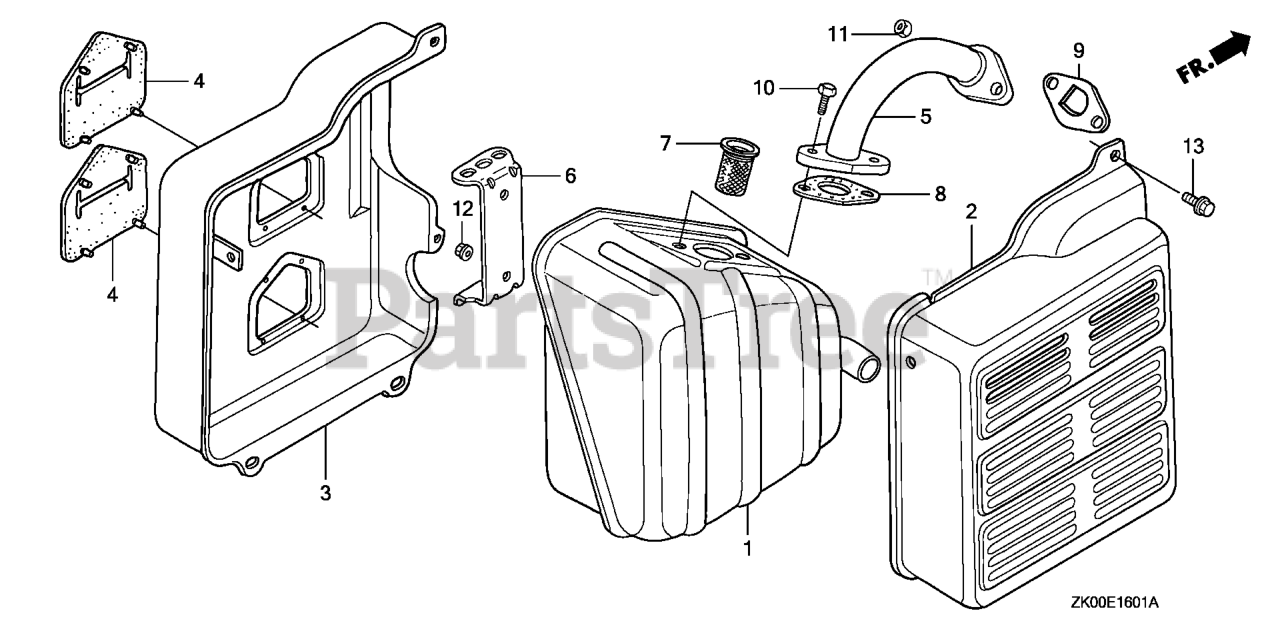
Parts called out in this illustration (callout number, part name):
7	ARRESTER, SPARK
9	GASKET, MUFFLER
11	NUT, HEX. (8MM)
